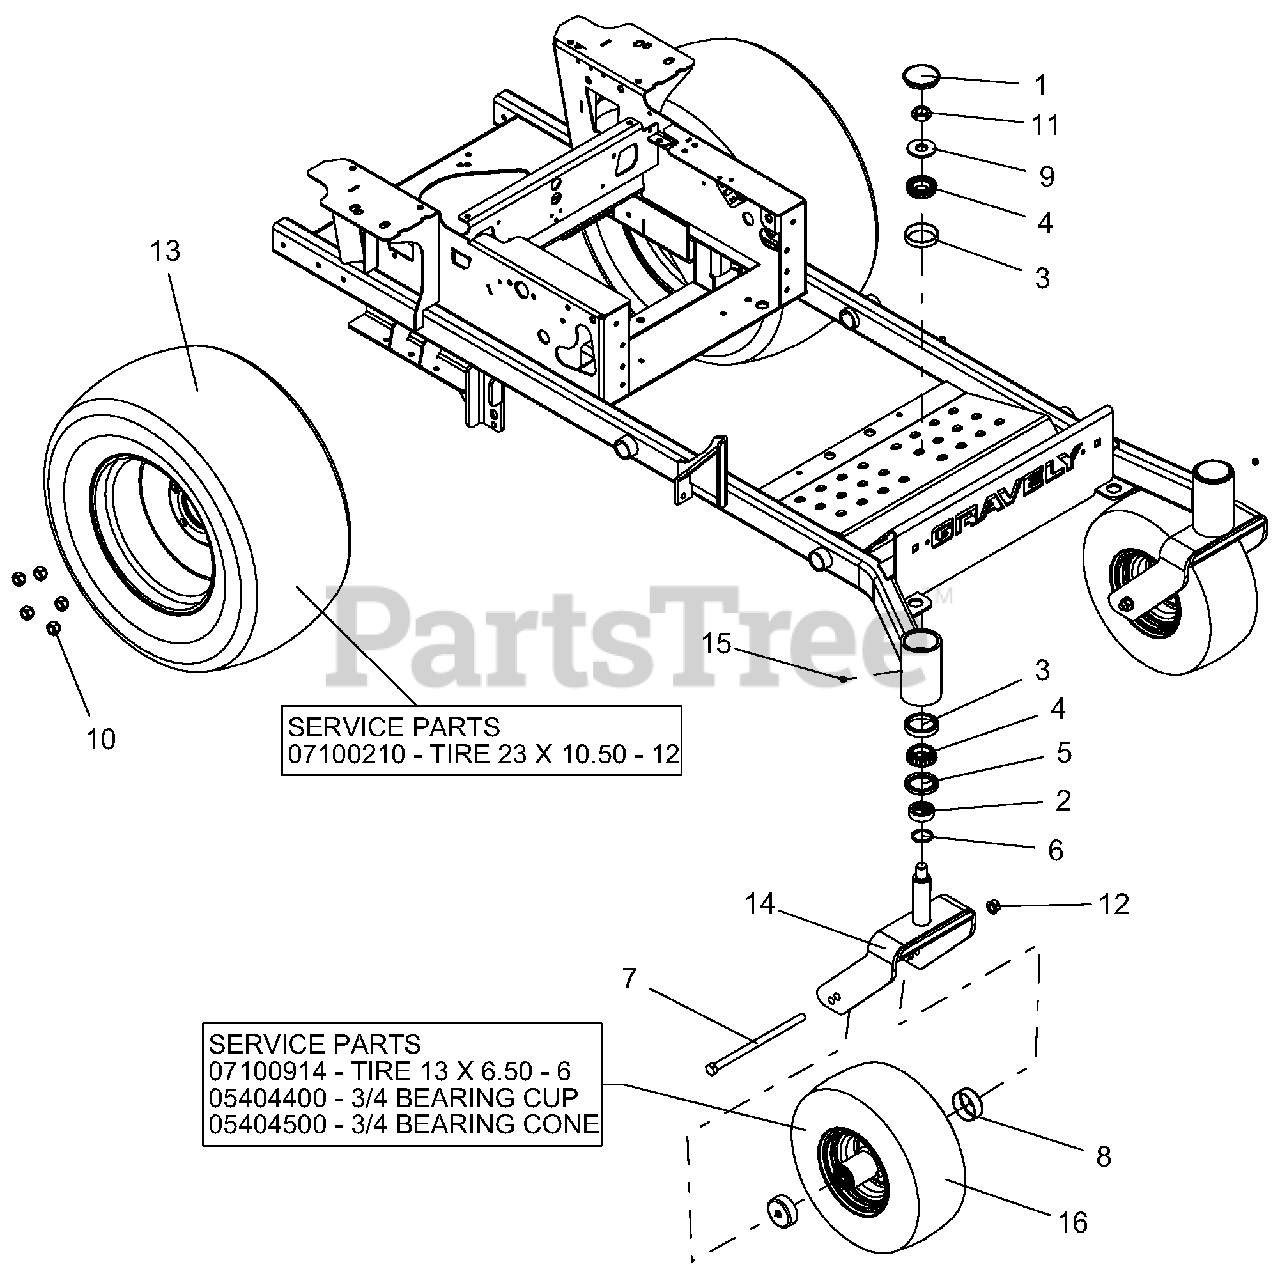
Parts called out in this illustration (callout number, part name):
1	CAP, DUST
2	SPCR, FRONT CASTER FORK
3	BRG, CUP 2.328X.465
4	BRG, CONE 1.25 X .66
5	SEAL, OIL 1.75 X 2.332 X .312
6	O-RING, .139 W X 1.234 ID
7	BLT-HEX .50-13X9.00 GR5 YWZC
8	SHIELD, WHEEL BEARING
9	WSHR-FL-STL.812X2.00X.148YWZC
10	NUT, LUG .500-13
11	@NUT-LK-CTR-JAM .75-16 YWZC
12	NUT, LK-TOP-FLG .50-13 YWZC
13	ASSM TIREWHEEL, 23X10-12
14	WMT, CASTER FORK - RED
15	PLUG, .250-28 X .185 HEX HEAD
16	TIRE/WHEEL, 13 X 6.50-6 SMOOTH
